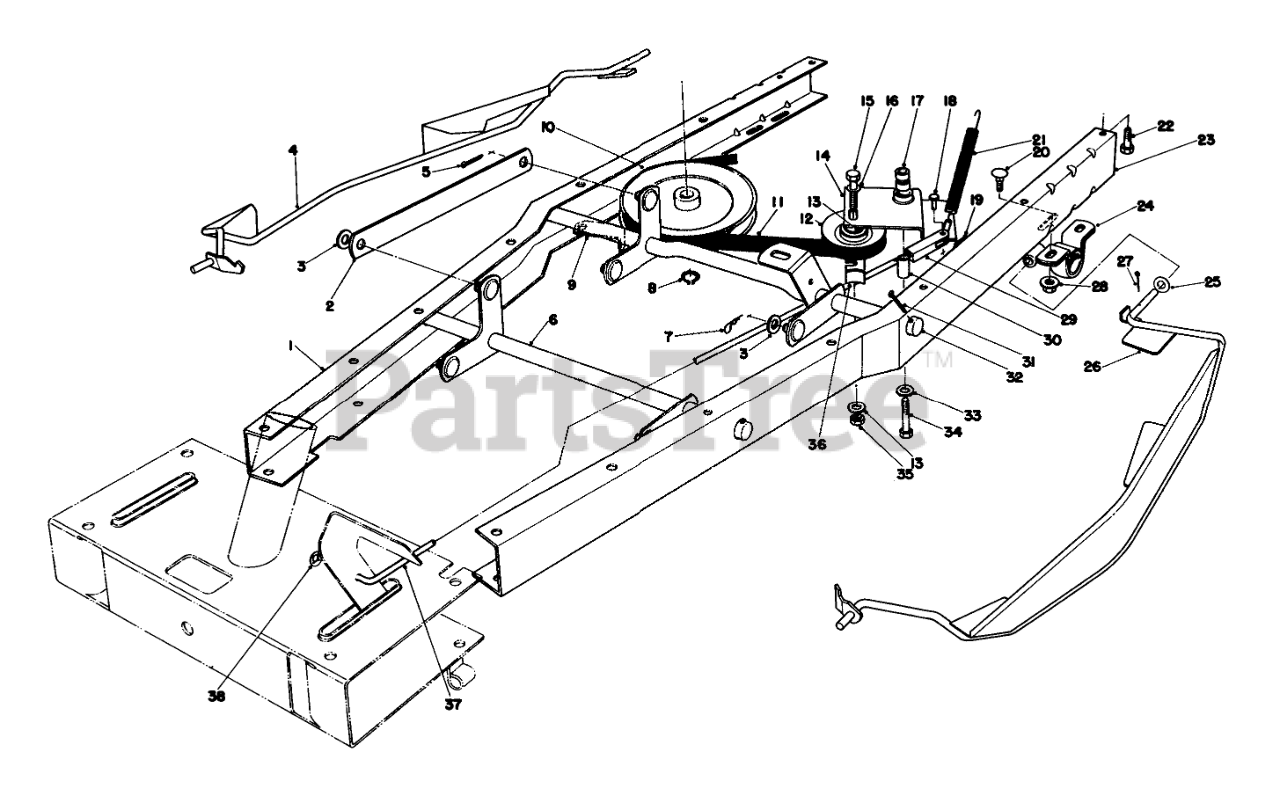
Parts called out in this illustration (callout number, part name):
1	Frame-Channel R.H.
2	Linkage-Height Adj.
3	WASHER-FLAT
4	Deck Shield R.H.
5	PIN-COTTER
6	FRONT LIFT WA B
7	PIN-COTTER
8	RING-SNAP, EXTERNAL
9	TRANS BELT RET B
10	PULLEY
11	V-BELT
12	PULLEY-IDLER
13	WASHER-FLAT
14	Traction Idler (Incl . Ref. #17)
15	SCREW-HH
16	Washer
17	Bushing
18	PIN-CLEVIS
19	Cotter Pin
20	SCREW-CARR
21	Clutch Tension Spring
22	SCREW-HH
23	Frame-Channel L.H.
24	PILLOW BLOCK
25	WASHER
26	Deck Shield L.H.
27	PIN-COTTER
28	NUT-HF
30	PIVOT SPACER
31	PIN-COTTER
32	REAR HT ADJ WA B
33	WASHER-PLAIN
34	SCREW-HH
35	NUT-LOCK, SIDE
36	RETAINER-BELT
37	Rod-Clutch
38	PUSH ON SPEED NUT 1/4
